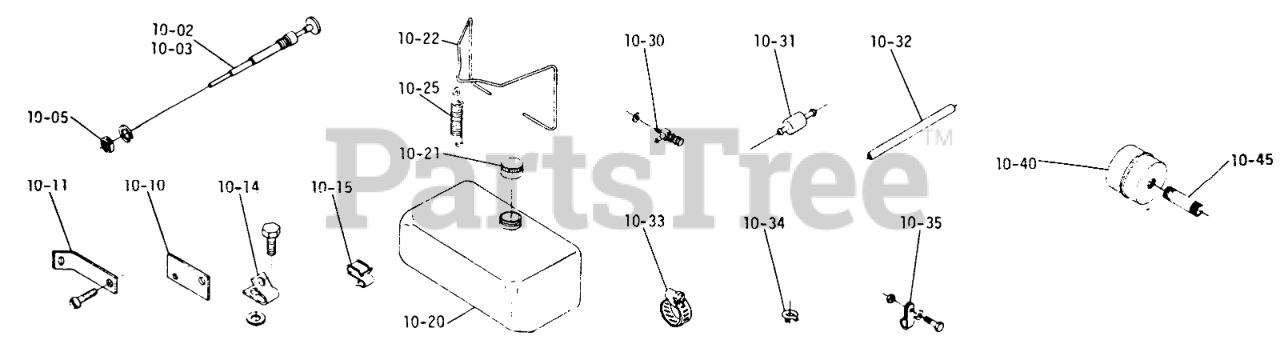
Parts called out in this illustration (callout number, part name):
10-05	RING NUT
10-05	Lockwasher 9/16
10-11	Bracket-Choke engine front
10-11	Screw, #10-32 x 5/8
10-14	CLIP BOWDEN WIRE
10-14	Screw #10 x 1/2 Type A
10-14	Speed Nut
10-30	S/A FUEL VALVE
10-35	Nut-Nylok
10-45	Nipple 3/4 Pipe x 3 1/2
